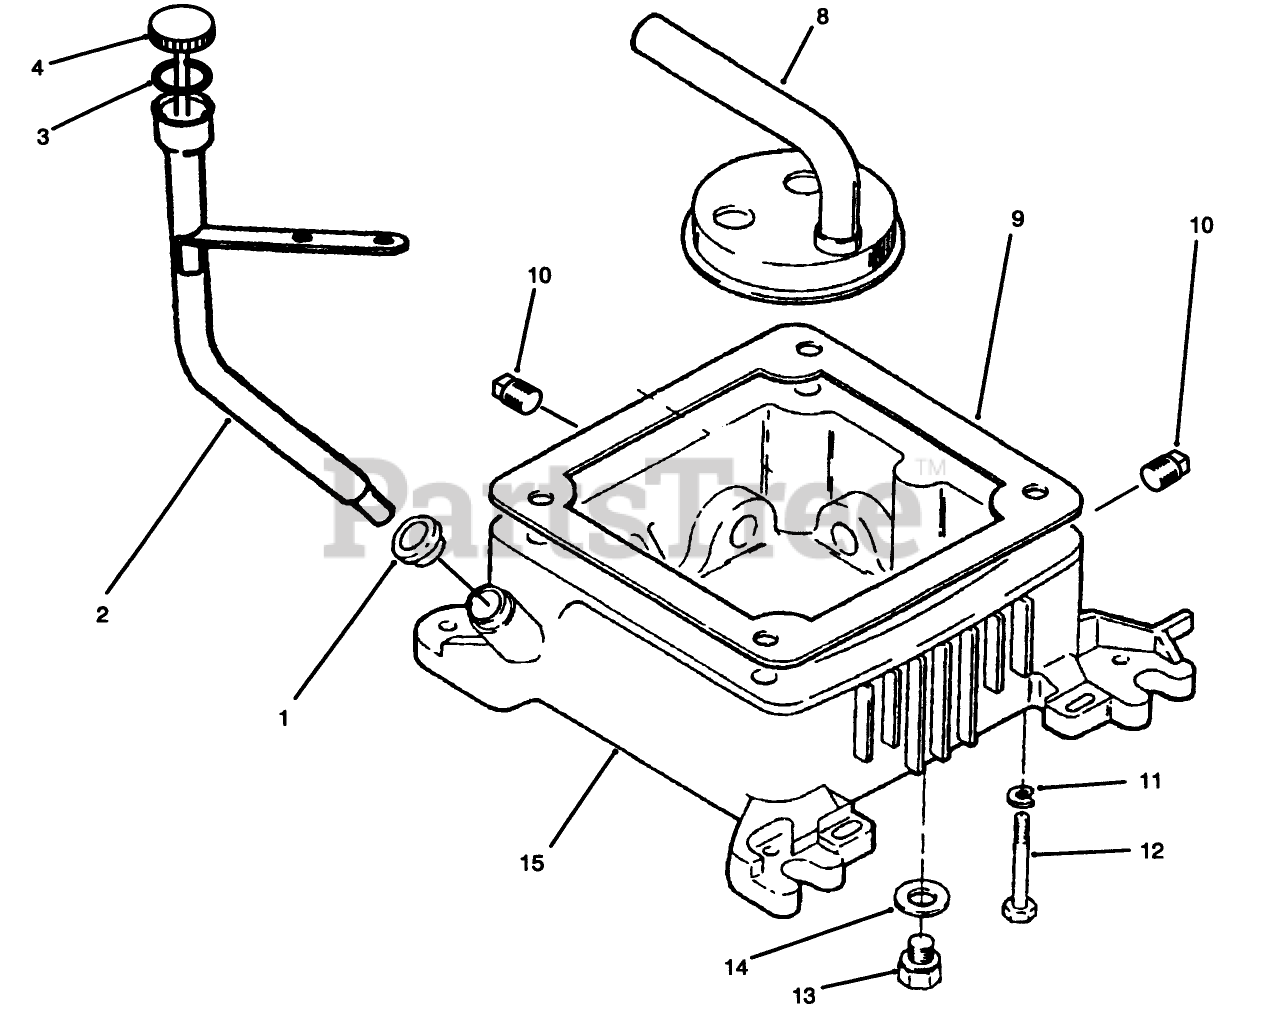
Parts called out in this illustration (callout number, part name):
1	SEAL-OIL FILL TUBE
2	OIL FILL TUBE W/BRKT
3	SEAL 0-RING
4	Cap (Incl. Ref. #3)
8	OIL CUP ASM
9	GASKET
10	PLUG-PIPE, SQH
11	WASHER-LOCK
12	SCREW-HH
13	PLUG-OIL
14	GASKET
15	Base (Incl.Ref. #9,10,13 & 14)
